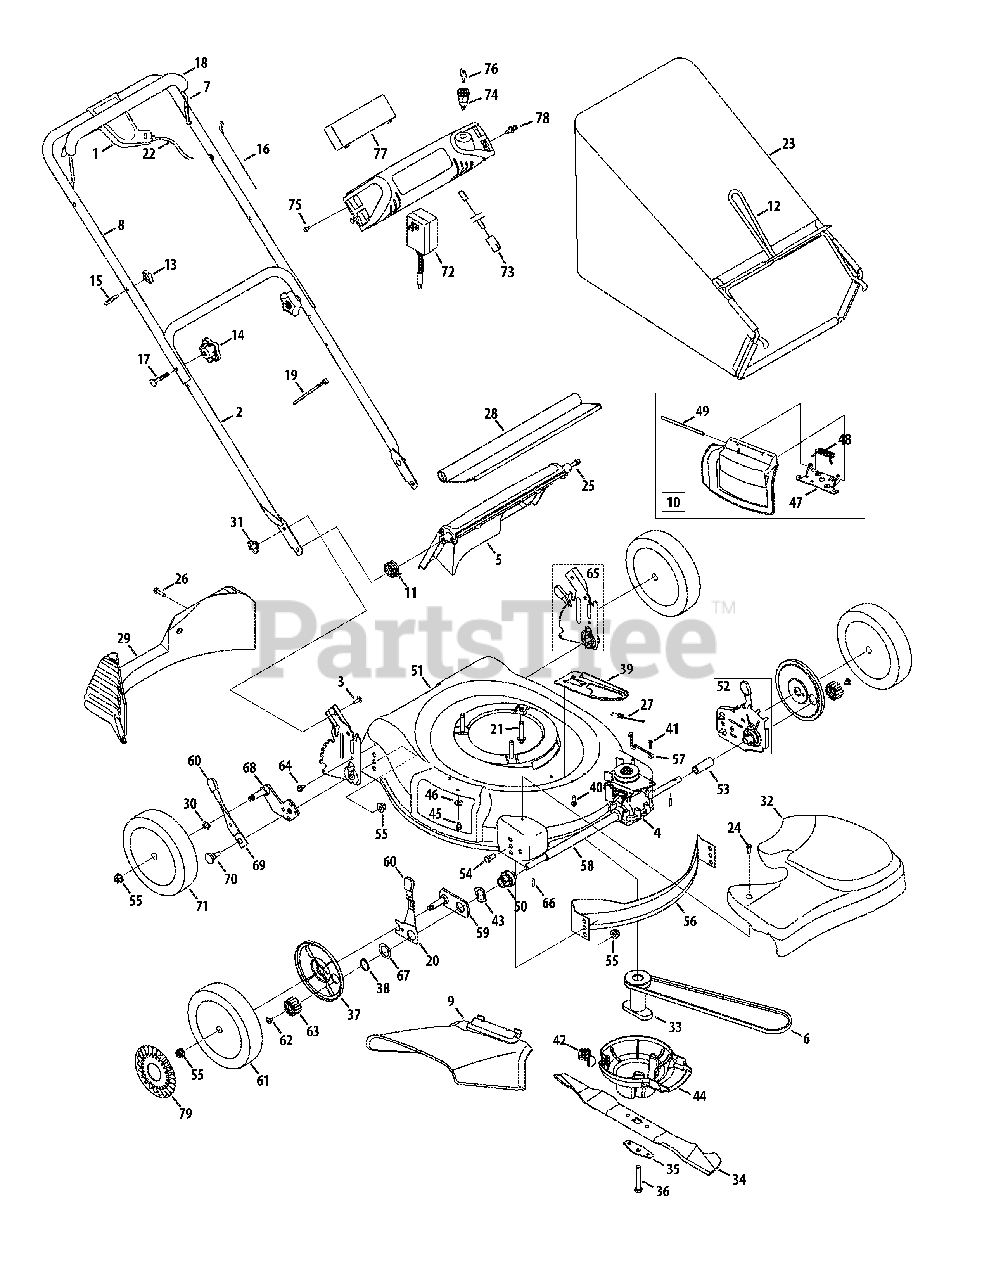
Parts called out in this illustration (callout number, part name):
1	Drive Control Assembly
2	Lower Handle
3	Carriage Bolt 1/4-20
4	Transmission Assembly
5	Rear Discharge Door
7	Blade Control
8	Upper Handle
9	Chute Deflector
10	Mulch Plug Complete
11	Torsion Spring - RH
13	Handle Knob
14	Handle Knob
15	Eye Bolt
16	Control Cable
17	Carriage Bolt 5/16-18 x 2.0
18	Bail Cover
19	Cable Tie
20	Front Lever - RH
20	Front Lever - LH
21	Self-Tapping Sems Screw
22	Drive Cable
23	Grass bag
24	Shoulder Screw # 12 -24
25	Pivot Rod
26	Screw, 1/4-15 x 1.00
27	Extension Spring
28	Rear Trailing Shield
29	Rear Baffle
30	Washer, Wave, .510 x .750 x .017
31	Wing Nut
32	Transmission Cover
33	One Piece Blade Adapter
34	21" Mulching Blade
35	Blade Bell Support
36	Hex Screw 3/8-24 x 2.50
37	Wheel Dust Cap
38	Snap Ring
39	Cable Mount Bracket
40	Screw, 1/4-14 x .625
41	Screw, .159 OD x .610
42	Engine Baffle Bracket
43	Washer, Wave, 1.5 x 1.0 x .029
44	Engine Baffle
45	TT Screw 1/4-20 x 0.5
46	Bell Washer.265 x 0.75
47	Deflector Chute Adapter
48	Torsion Spring
49	Hinge Pin
50	Bearing Assembly
52	Height Adjustment Ass’y - RH
52	Height Adjustment Ass’y - LH
53	Sleeve Spacer, 1.8" Lg.
54	Hex Screw, 3/8-16 x.75
55	Flange Lock Nut, 3/8-16
56	Front Baffle
57	Belt Keeper Wire
58	Sleeve Spacer, 9.10" Lg.
59	Pivot Plate Assembly
60	Adjustment Knob
61	Front Wheel
62	Screw, 1/4-20 x .390
63	Gear 14T RH FWD
63	Gear 14T LH FWD
64	TT Scr. w/Washer 1/4-20 x.625
65	Handle Bracket Assembly - RH
65	Handle Bracket Assembly - LH
66	Dowel Pin
67	Washer
68	Pivot Arm Assembly - RH
68	Pivot Arm Assembly - LH
69	Rear Spring Lever
70	Shoulder Scr., 500 Dia. x. 385
71	Rear Wheel
72	Battery Charger
73	Electric Start Harness Assembly
74	Key Switch
75	Screw, #10-16 x .750
77	Battery
78	Rivet
